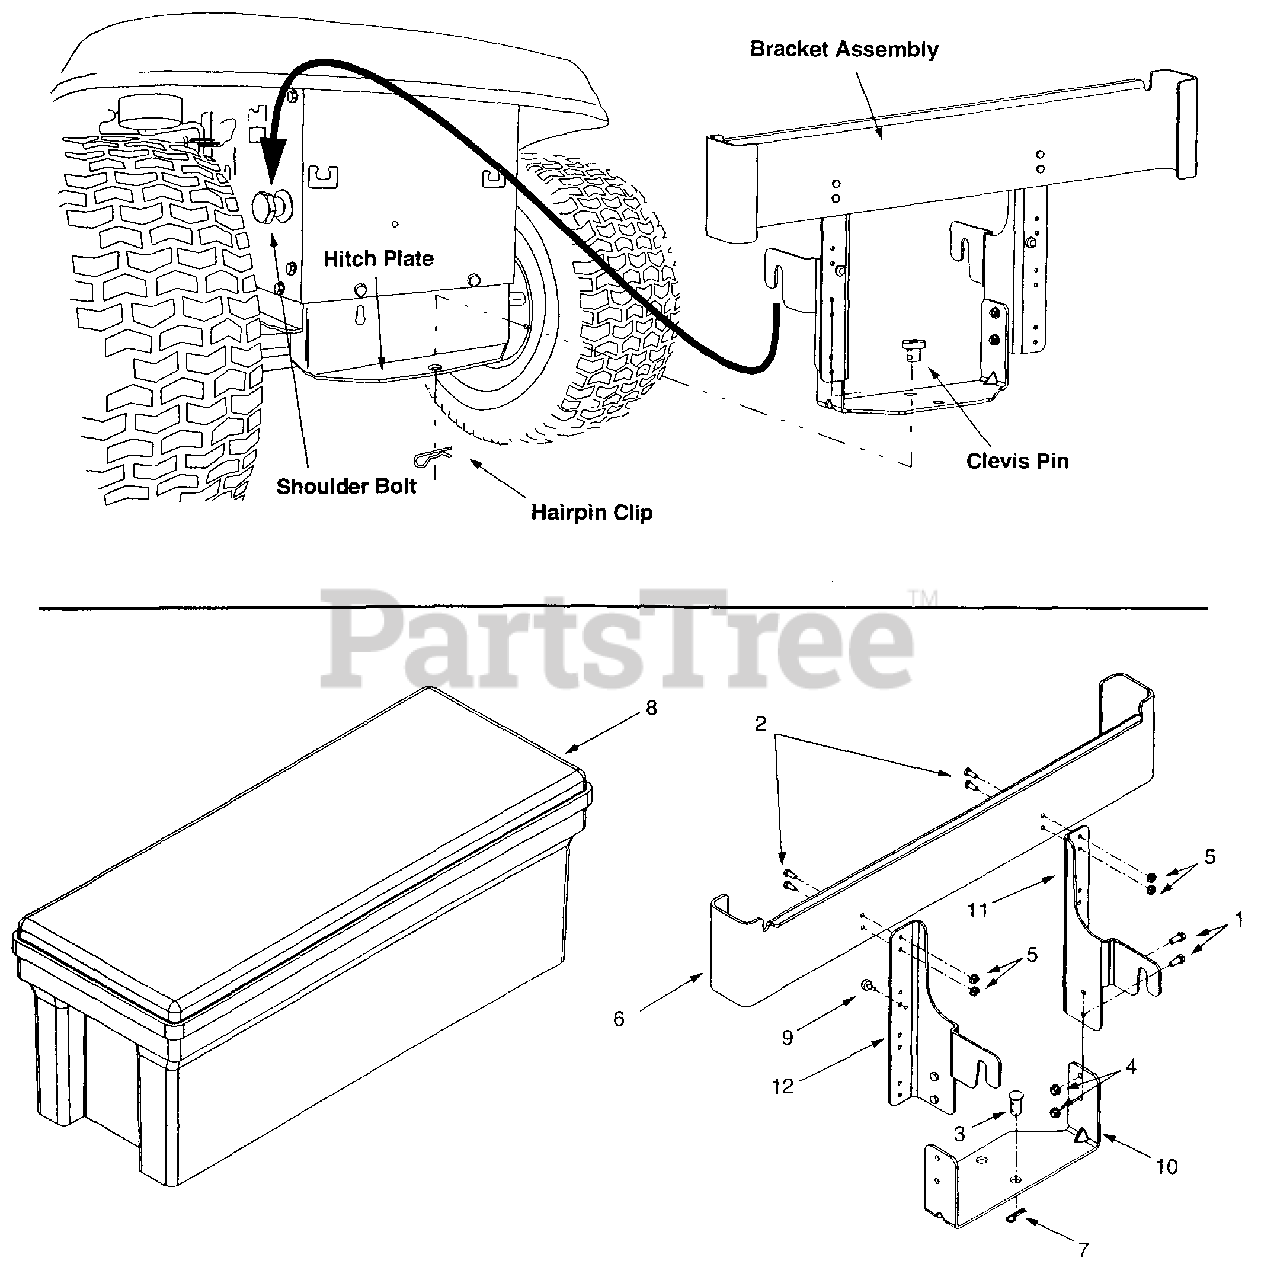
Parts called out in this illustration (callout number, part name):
1	Hex Cap Screw, 5/16-18 x .75
2	Hex Cap Screw, 1/4-20 x .62
3	Clevis Pin
4	Hex Flange Lock Nut, 5/16-18
5	Hex Flange Lock Nut, 1/4-20
8	Plastic Tool Box
9	Bumper, .62 Dia. x .3
10	Cross Support Bracket
11	LH Support Bracket
12	RH Support Bracket
